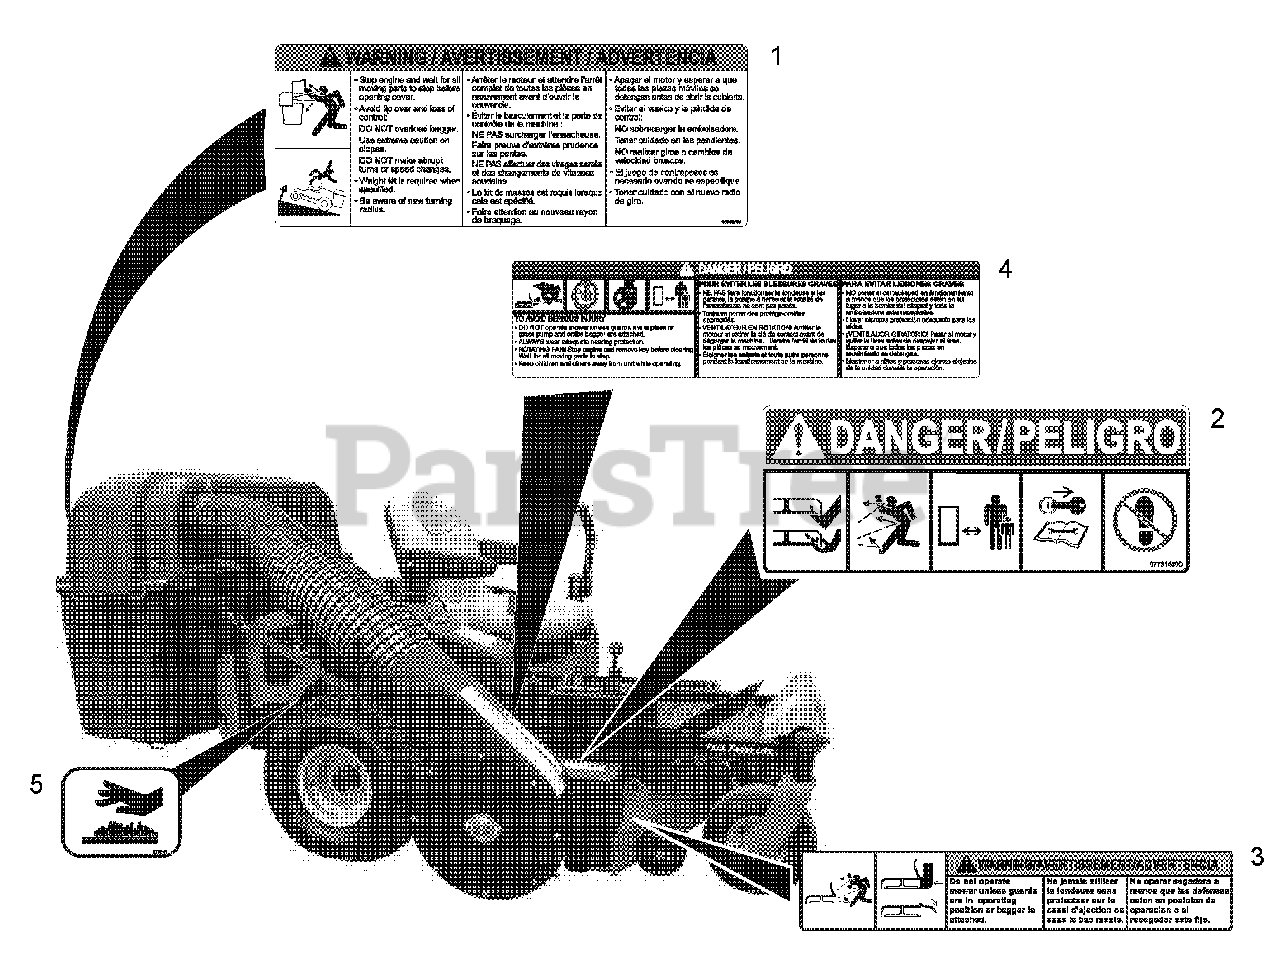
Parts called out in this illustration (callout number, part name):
1	DECAL, BAGGER COVER
2	DECAL, MOWER PAN DANGER
3	DECAL, WARNING
4	DECAL-CAUTION, GRASS PUMP
5	DECAL, HOT SURFACE
